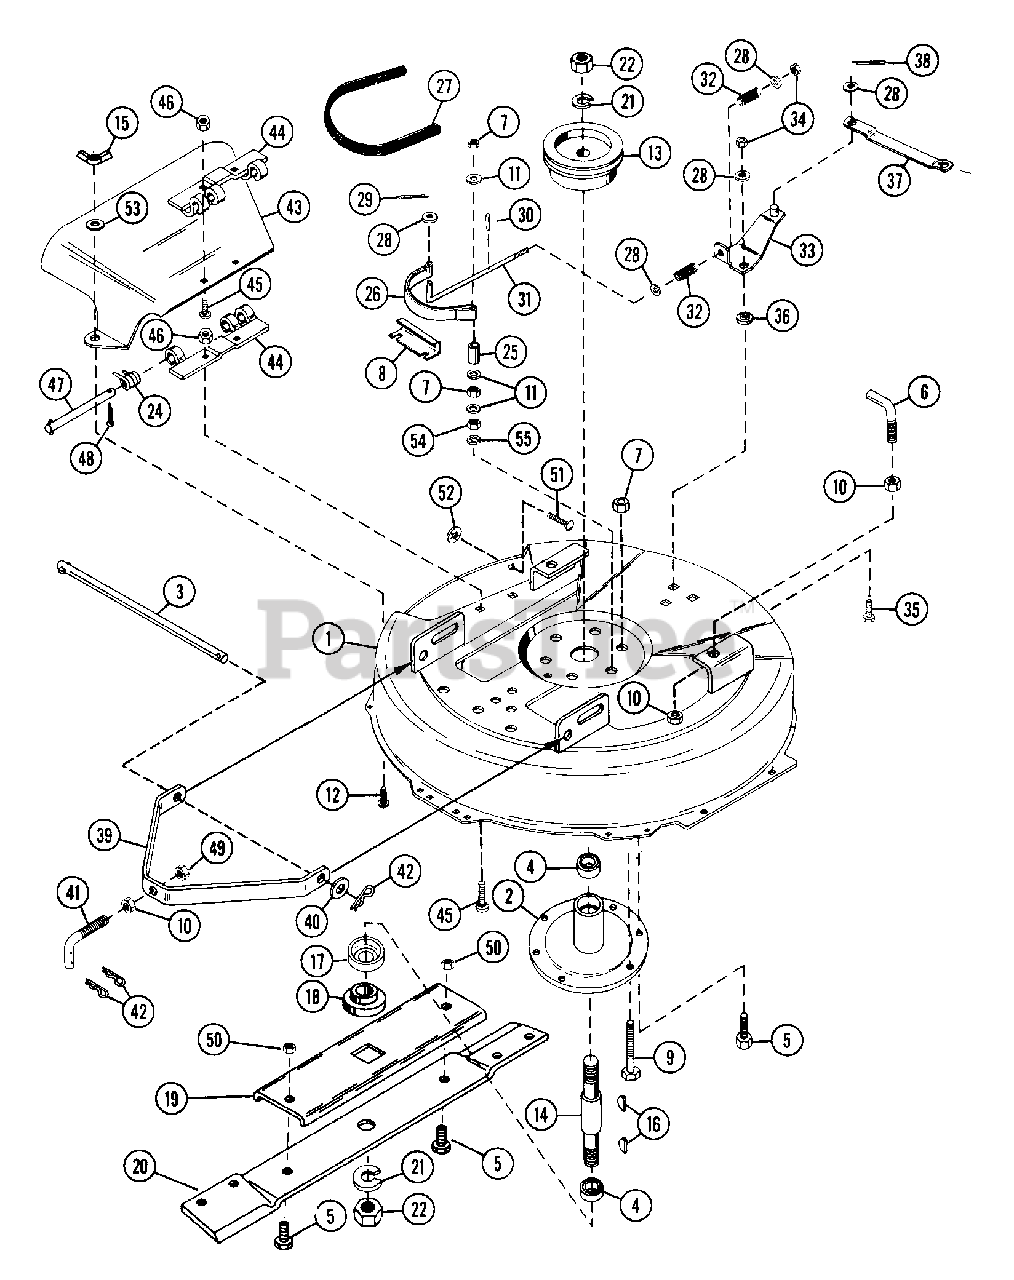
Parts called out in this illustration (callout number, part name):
1	32 IN MOWER PAN SERVICE ASSEMB
2	SPINDLE HOUSING
3	TOW PIN
4	BRG-BALL .750X1.781X.61
5	BLT-HEX .38-16X1.00 PL GR5
6	HANGER HOOK
7	NUT-LK-CTR .375-16 GR A PL
8	BRAKE BAND SUPPORT
9	BLT-HEX .38-16X3.00 PL GR5
10	NUT-JAM .50-13 PL
11	WSHR-FL-STL.406X.812X.065PL
12	BLT-RDHDSQNK .31-18X.75 GR5 PL
13	MOWER SHEAVE
14	SPINDLE SHAFT
15	NUT-WING W/INSERT .312 - 18
16	KEY-WDRF .188X.75X.313 SAE 9
17	BEARING SLINGER
18	RETAINER HUB
19	BLADE TRAY
20	MOWER BLADE 32
21	WSHR-LK .750X.188 MED PL
22	NUT-JAM .75-10 PL
24	SG-TORS .090X.37X.63
25	SPACER .386X.502X1.060
26	BRAKE BAND
27	V-BELT, 4L-RAW EDGE
28	WSHR-FL-STL .323X.625X.062 PL
29	PIN-COTR .06X.50
30	PIN-ROLL .125X1.00
31	BRAKE ROD
32	SG-COMP .057X.47X1.25
33	BRAKE ACTUATOR
34	NUT-LK .312-18 GR A PL
35	BLT-HEX .31-18X.75 PL GR5
36	SPACER -FLANGED .325X.498X.318
38	PIN-COTR .12X1.0 PL
39	MOWER STRAP
40	WSHR-FL-STL .505X.880X.072 PL
42	PIN-HAIR INT .09X.188 PL
43	CHUTE DEFLECTOR W/ DECAL
44	HINGE PLATE
45	BLT-RDHDSQNK .25-20X.62 PL
46	NUT-LK-CTR .250-20 PL
47	CLEVIS PIN
48	PIN-COTR .09X.75 PL
49	NUT-LK-CTR .50-13
50	NUT-LK TOP .375-16 GR C YWZC
51	BLT-RDHDSQNK .312-18X.62SHTPL
52	NUT-PUSH .312
53	WSHR-FL-STL .328X.875X.062 PL
54	NUT-HEX .375-16
55	WSHR-LK .375X.115 HVY PL
